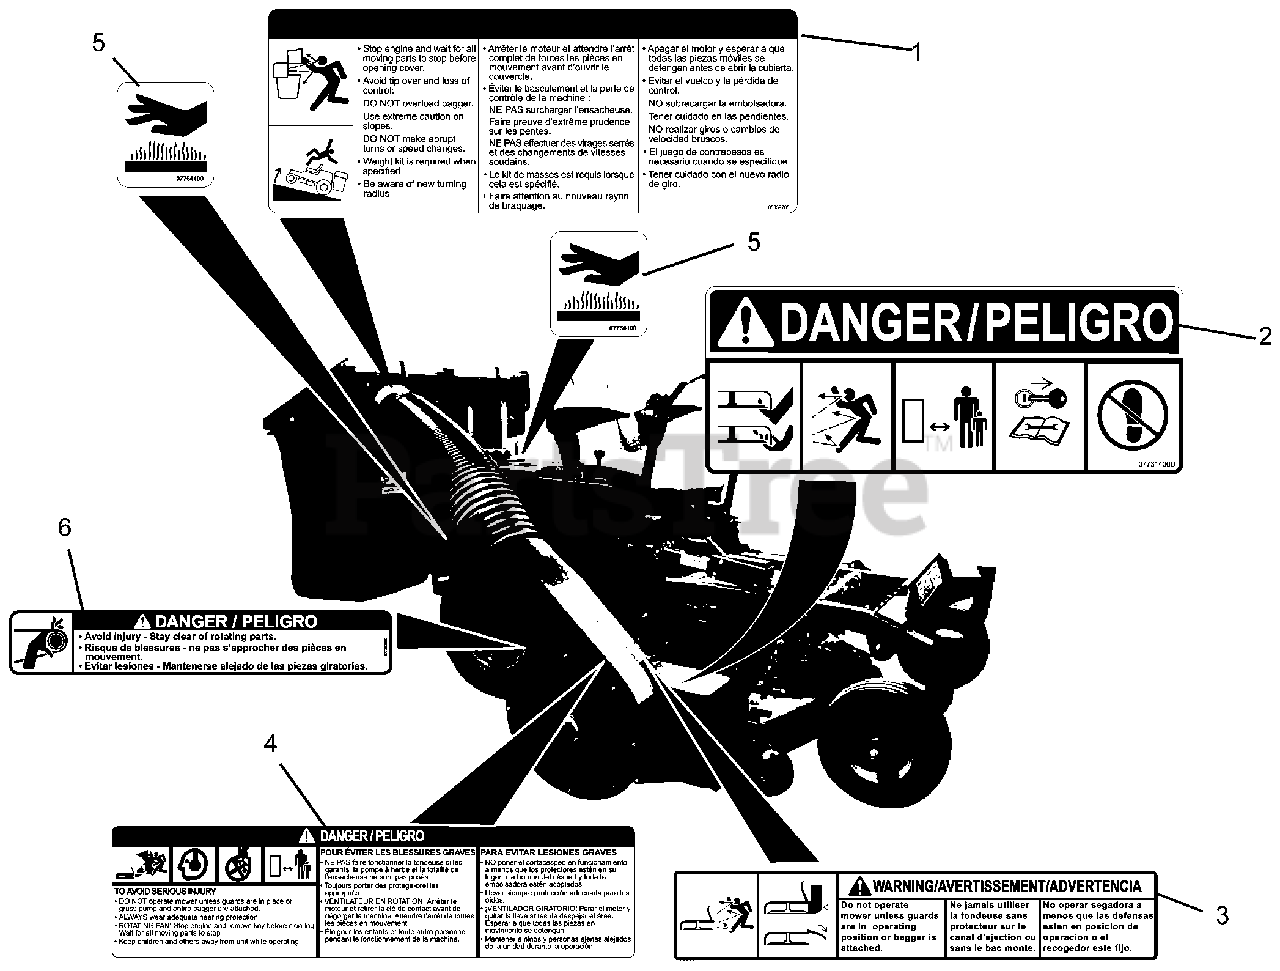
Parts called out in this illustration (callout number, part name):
1	Bagger Cover Decal
2	Mower Pan Danger Decal
3	Warning Decal
4	Grass Pump Caution Decal
5	Decal, Hot Surface
6	Decal, Belt Pinch Point
